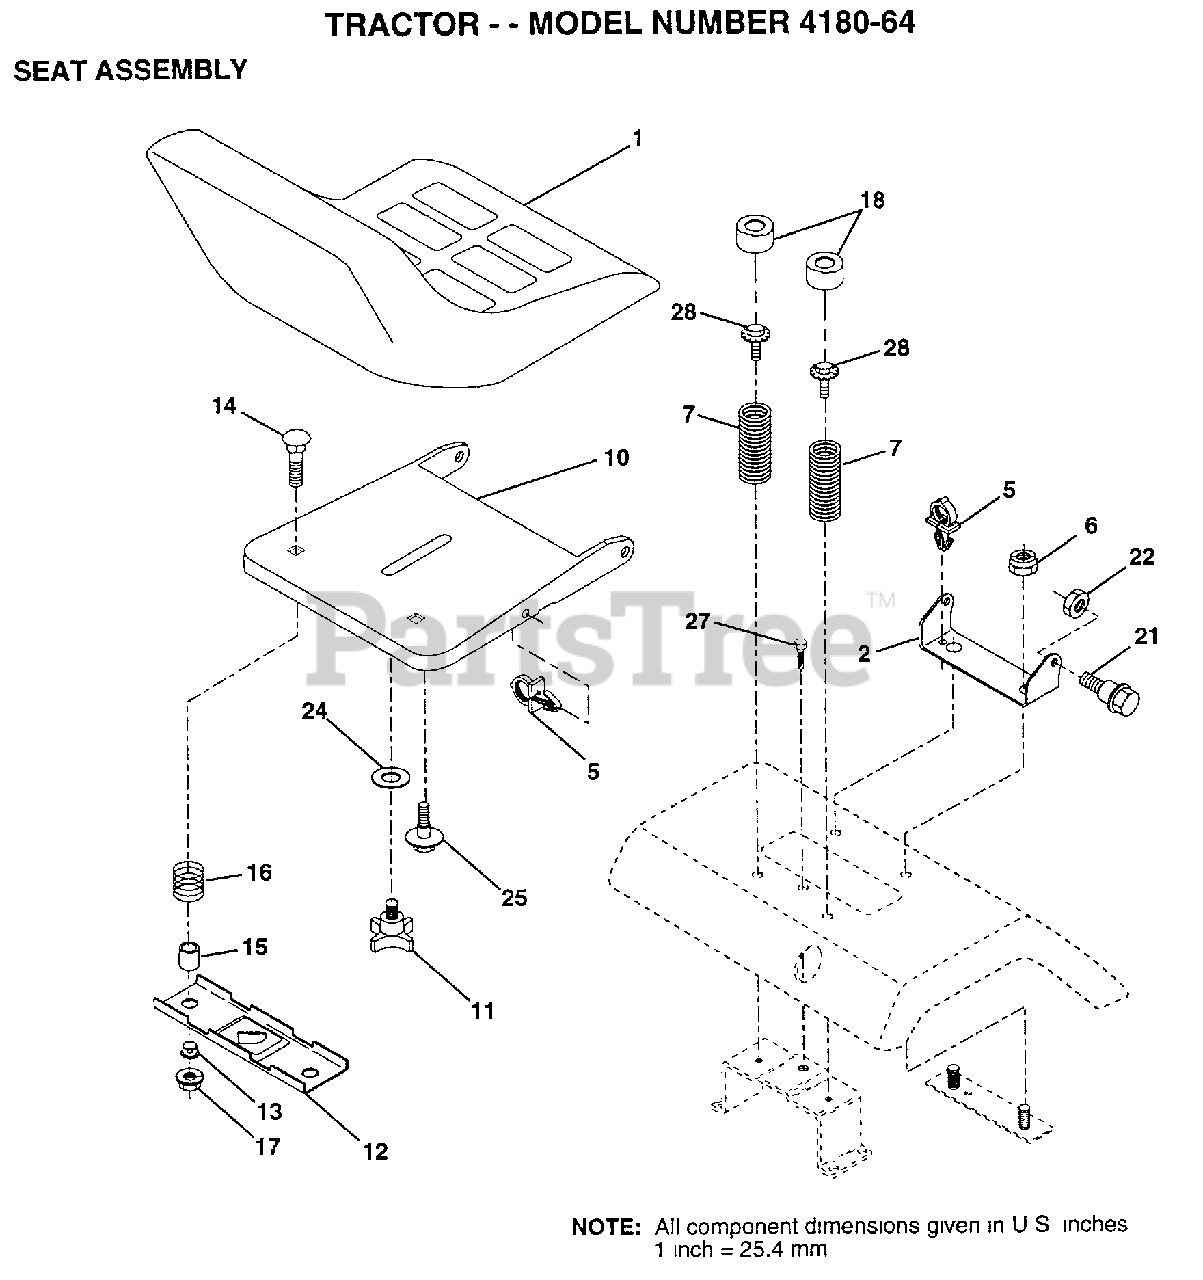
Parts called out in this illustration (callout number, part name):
2	BRACKET PVT SEAT
5	CLIP.PUSH-IN.HING
6	NUT
7	SPRING COMPRESSIO
11	"KNOB 1/2"" YT"
12	BRKT SWITCH
13	BUSHING
15	SPACER SPLIT
16	SPRING COMPRESSED
18	CAP SPRING
21	"BOLT,SHOULDER"
24	WASHER
25	"BOLT,SHOULDER"
27	SCREW LT
28	BOLT.5/16-18.UNC
